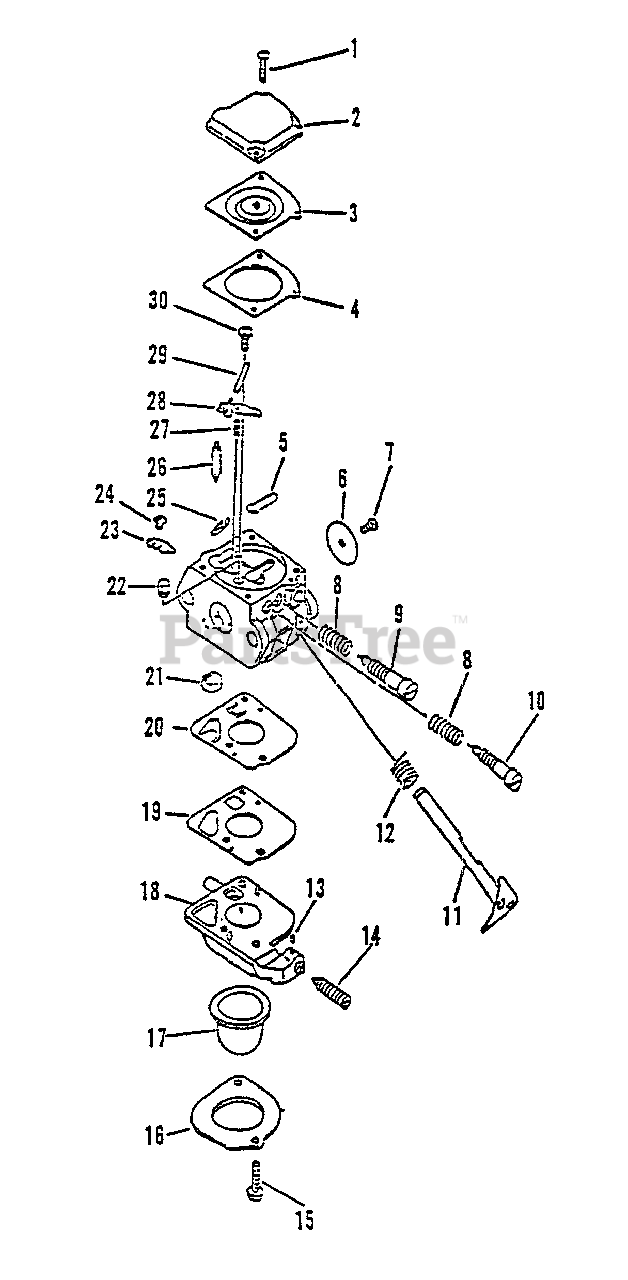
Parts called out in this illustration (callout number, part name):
2	COVER, METERING
3	DIAPHRAGM
4	GASKET, METERING
5	PLUG, WELCH
6	VALVE, THROTTLE
9	NEEDLE - MIXTURE
10	NEEDLE - MIXTURE
11	SHAFT, THROTTLE
12	SPRING, RETURN
13	PIECE, FRICTION
14	SCREW, IDLE ADJUST
15	SCREW, RETAINER
16	RETAINER, PURGE BULB
17	BULB, PURGE
18	BASE, PURGE
19	GASKET, PURGE
20	DIAPHRAGM, PURGE
21	STRAINER
22	NOZZLE, CHECK VALVE
23	LEVER, THROTTLE
25	RING, RETAINING
26	VALVE, NEEDLE
27	SPRING
28	LEVER, METERING
29	PIN
30	SCREW, METERING LEVER PIN
